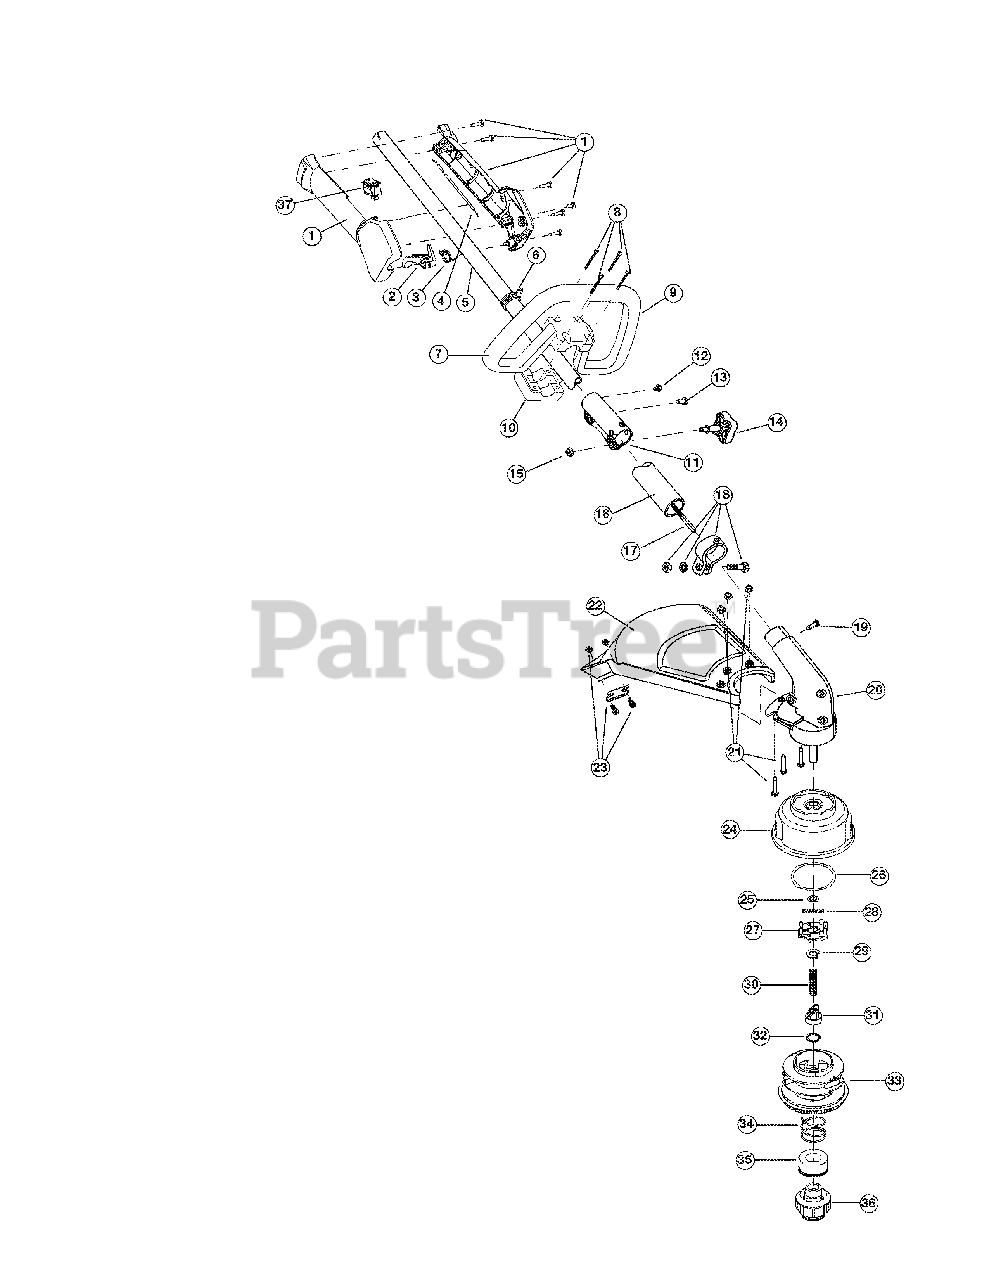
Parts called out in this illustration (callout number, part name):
1	Throttle Housing Assembly (includes 2 & 37)
2	Throttle Trigger
3	Throttle Trigger Spring
4	Throttle Cable Assembly
5	Upper Drive Shaft Housing Assembly
6	Harness Clip
7	Deluxe D-Handle Assembly (includes 8-10)
9	Deluxe D-Handle
10	Bottom Clamp
11	Split Boom Coupler (includes 12-15)
14	Adjustment Knob (includes 15)
15	Knob Retaining Nut
16	Lower Drive Shaft Housing Assembly
17	Lower Flexible Drive Shaft
18	Lower Clamp Assembly (includes 19)
19	Anti-Rotation Screw
20	Gear Box Assembly (includes 24 & 25)
21	Shield Mounting Hardware
22	Shield Assembly (includes 23)
23	Blade Assembly
24	Outer Spool Assembly (includes 25)
26	Thrust Washer
28	Small Spring
33	Inner Reel
34	Large Spring
36	Bump Head Knob Assembly (includes 34 & 35)
